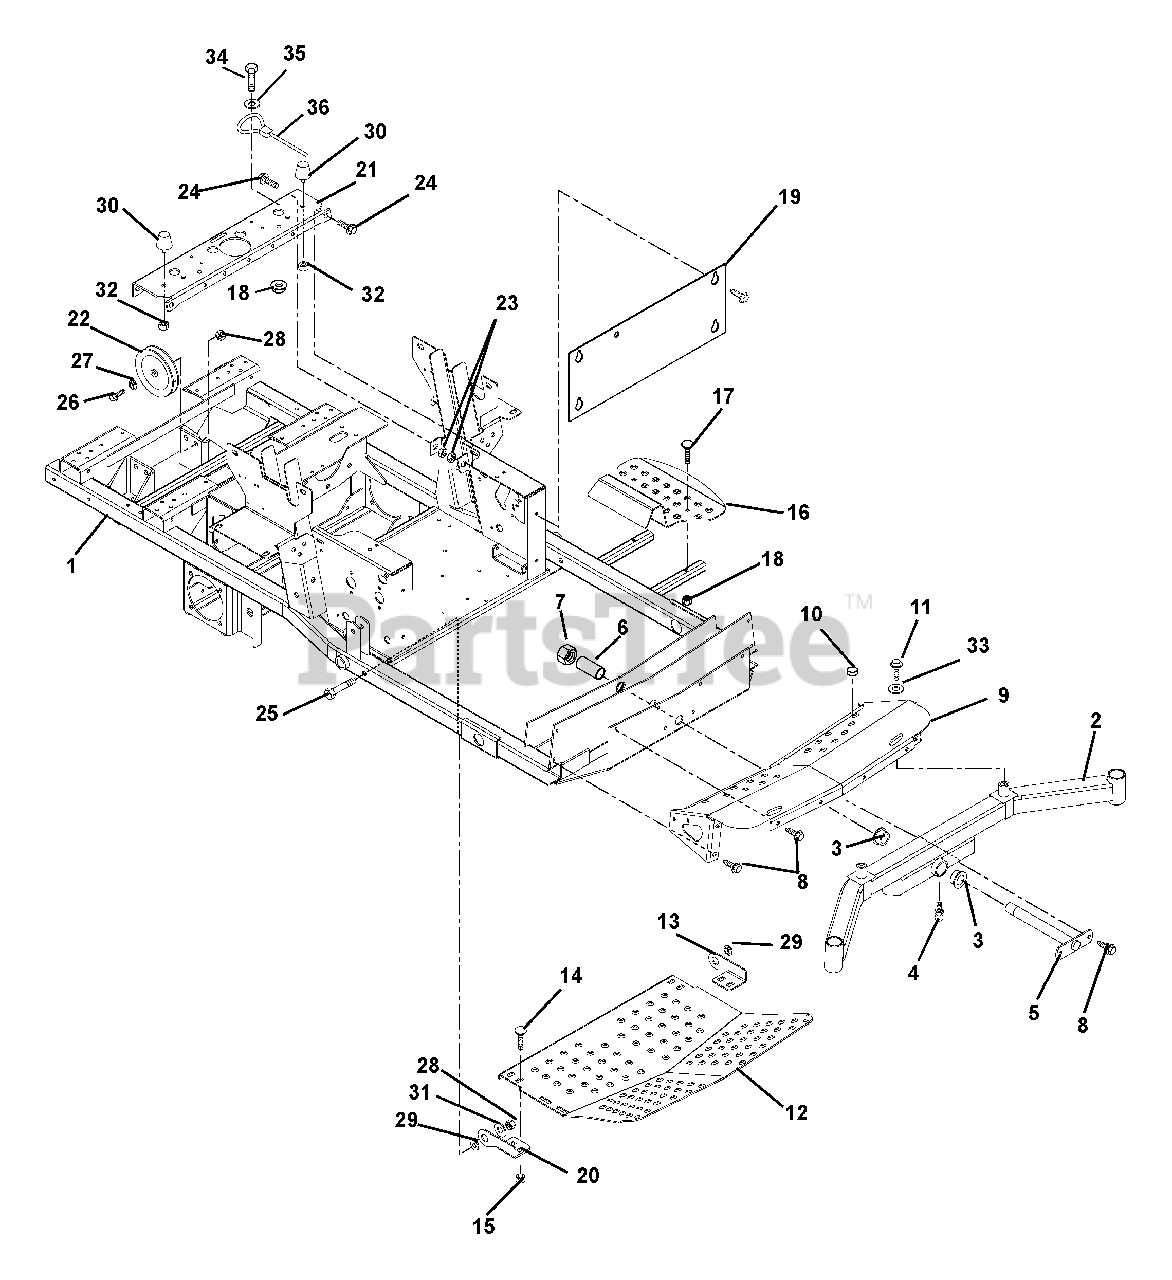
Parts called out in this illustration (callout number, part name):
1	Weldment, Frame
2	Weldment, Front Axle
3	Bushing, Flange 1.020 x 1.385 x .75 x 1.75
4	Fitting, Lube .25-28 x .256
5	Pin, Axle
7	Nut, Locking Nylon 1.0-14
8	Screw, Tapping .38-16 x .75
9	Weldment, Axle Cover
10	Button, Bumper
11	Bolt, Hex .50-20 x 1.00 Grade 5
12	Panel, Inspection
13	Hinge, Footboard Left Hand
14	Bolt, Round Head Square Neck .38-16 x 1.00 Grade 5
15	Nut, Locking Top Flange .38-16
16	Step, Ingress
17	Bolt, Round Head Square Neck .31-18 x 1.75 Grade 5
18	Nut, Locking Top Flange .31-18
19	Plate, Kick
20	Hinge, Footboard Right Hand
21	Channel, Cross
22	Pulley, Idler
23	Nut, Retainer .375-16 x .37
24	Bolt, Serrated Flange Washer Head .38-16 x 1.00
25	Bolt, Hex .50-13 x 3.25 Grade 5
26	Bolt, Hex .50-13 x 2.25 Grade 5
27	Washer, Flat Steel .505 x .88 x .072
28	Nut, Locking Top Flange .50-13
29	Bushing, Flange .515 x .75 x .275 x 1.12
31	Washer, Flat Steel .563 x 1.38 x .109
32	Nut, Locking Flange .312-24
33	Washer, Flat Steel .064 x 1.810 x .250
34	Bolt, Hex .31-18 x .75 Grade 5
35	Washer, Flat Steel .328 x 1.00 x .094
36	Cable, Seat Prop
